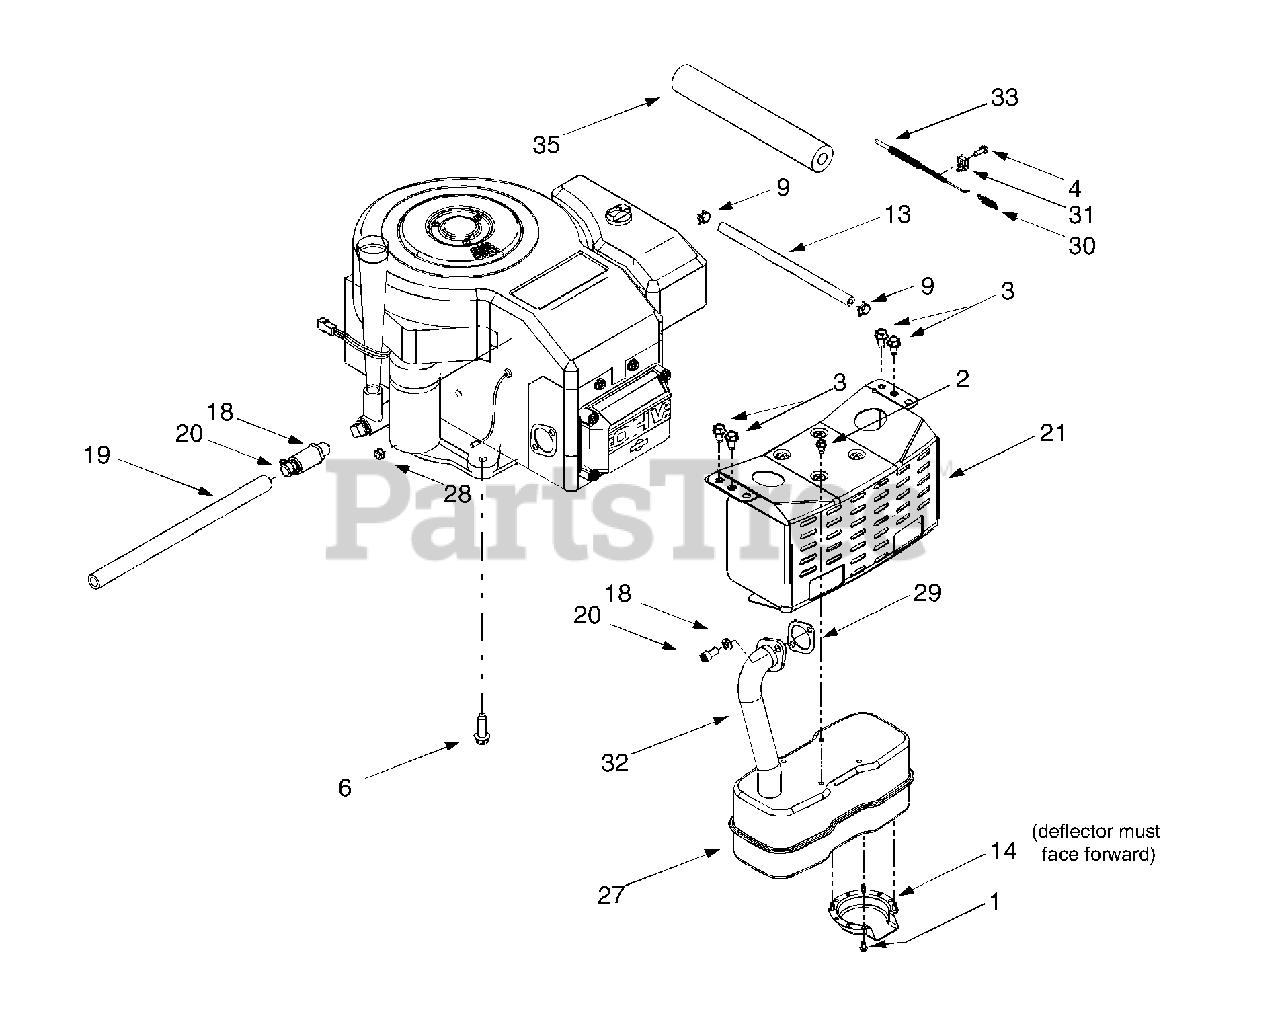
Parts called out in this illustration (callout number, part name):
1	Self-tapping Screw, #8-32 x .375
2	Self-tapping Screw, 1/4-20 x .5
3	Self-tapping Screw, 5/16-18 x .625
4	Screw, #10-32 x .625
6	Self-tapping Screw, 3/8-16 x 1.25
9	Hose Clamp
13	Fuel Line Hose
14	Muffler Deflector
18	Oil Drain Valve
19	Oil Drain Hose
20	Oil Drain Cap
27	Muffler, Single Inlet
28	Hex Sems Nut, 1/4-20
29	Exhaust Gasket
30	Extension Spring, .275 x 1.25
31	Casing Clamp
32	Exhaust Pipe
33	Throttle/Choke Cable
35	Foam, .625 x 1.5 x 10
